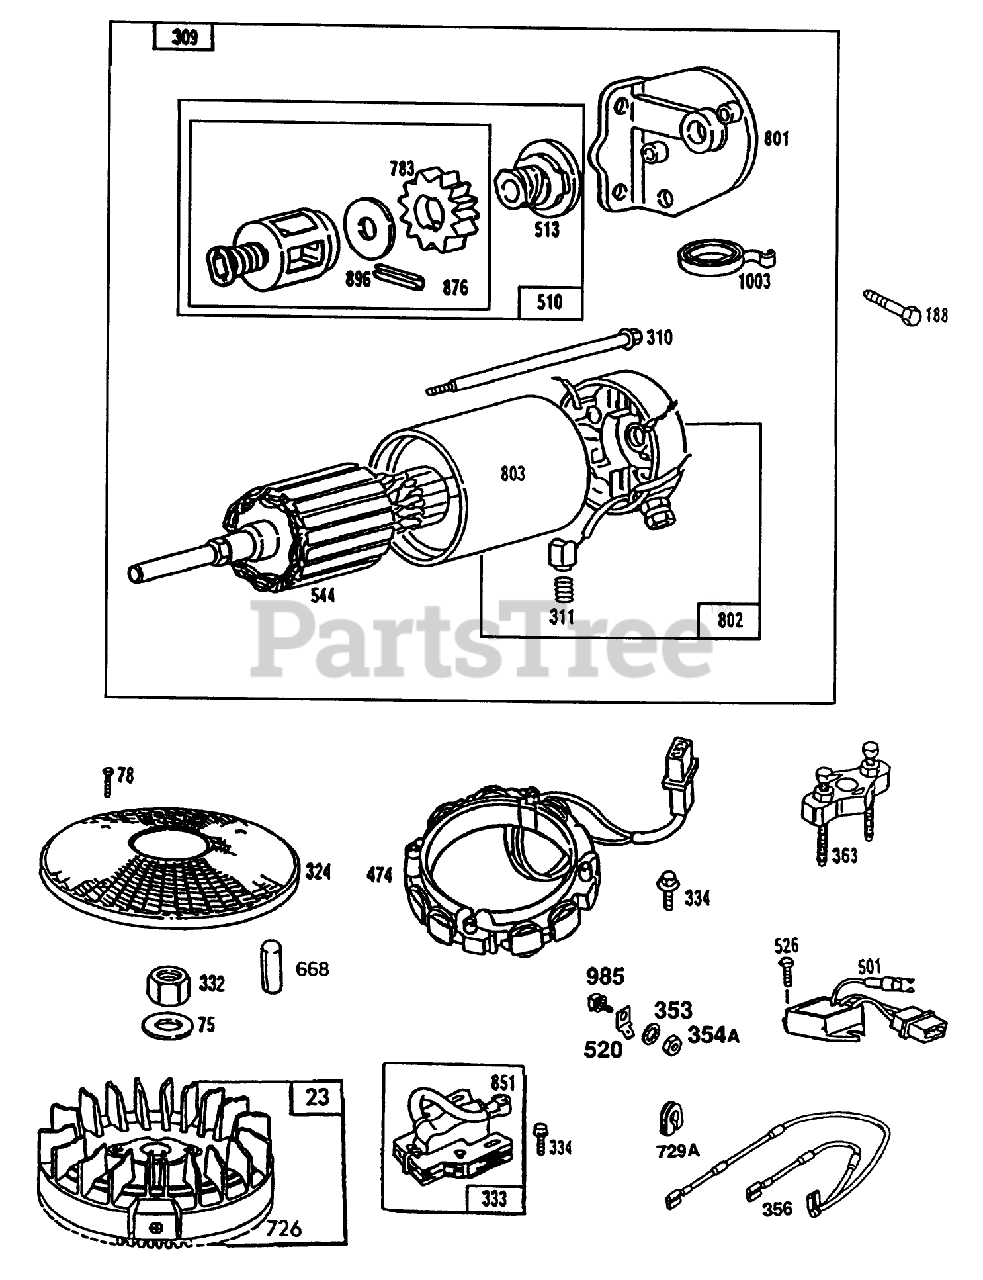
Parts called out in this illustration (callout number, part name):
75	BRIGGS-805007
78	BRIGGS-805447
188	BRIGGS-805247
310	BRIGGS-94169
311	BRIGGS-490311
324	BRIGGS-494439
332	BRIGGS-805021
334	BRIGGS-805407
356	BRIGGS-493792
363	BRIGGS-19203
513	BRIGGS-398003
526	BRIGGS-805448
668	BRIGGS-807688
803	BRIGGS-399172
876	BRIGGS-490467
896	BRIGGS 94288
985	Insulator
1003	BRIGGS-805025
